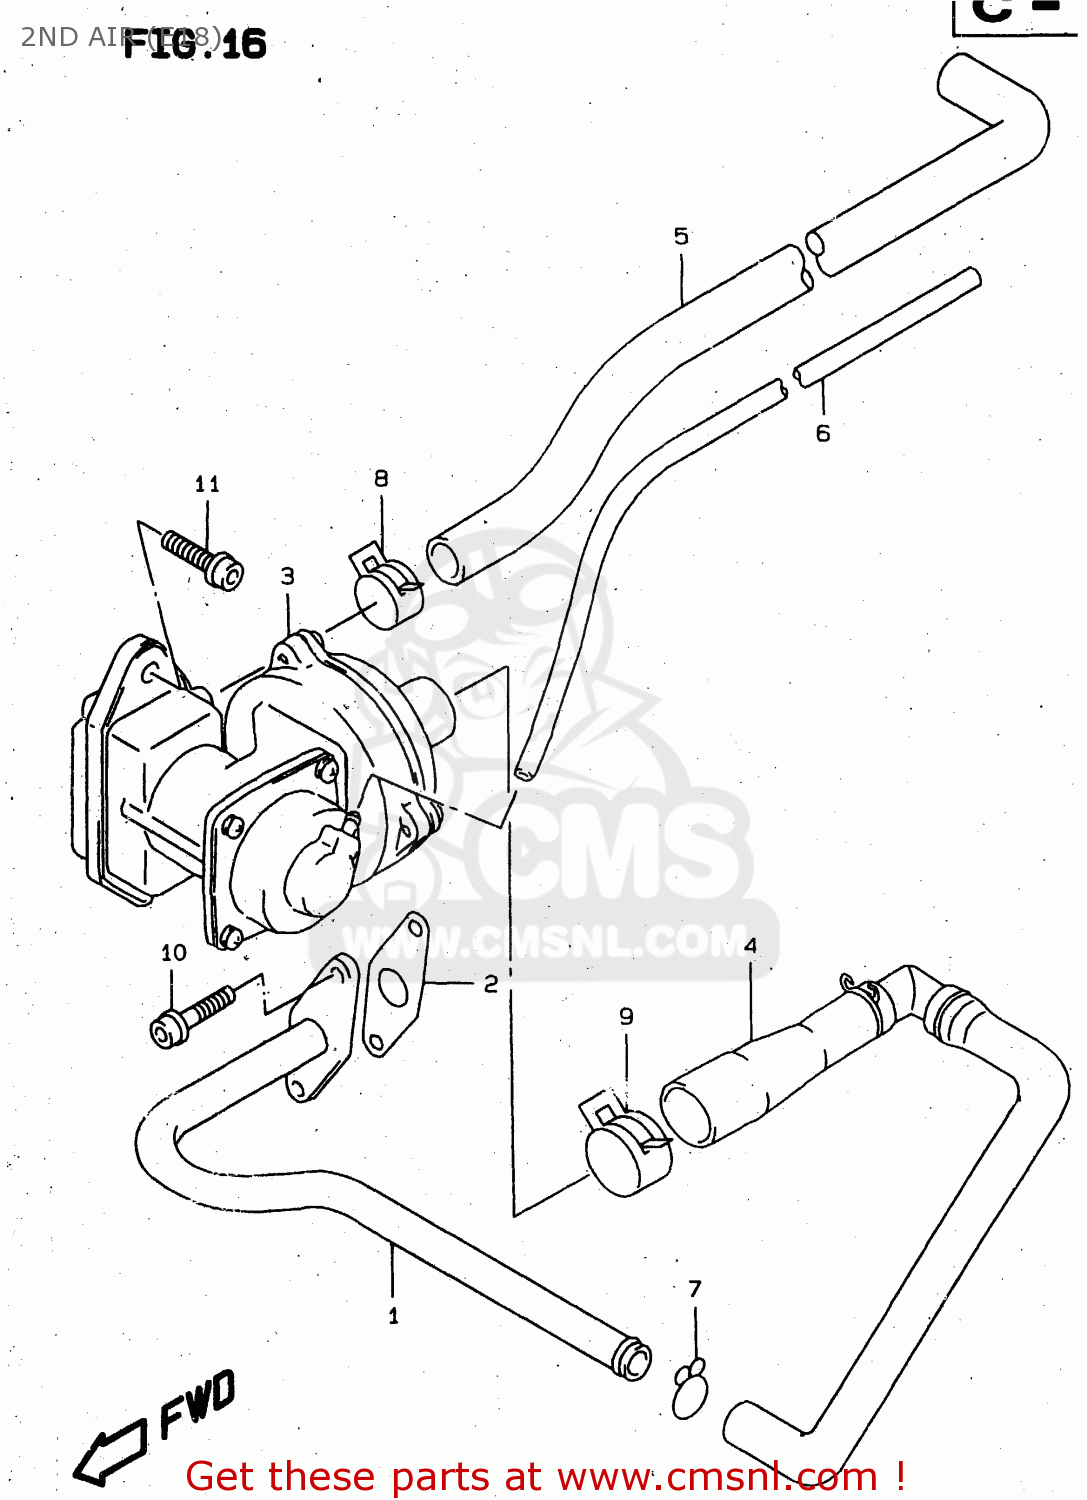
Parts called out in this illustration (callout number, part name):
1	PIPE, 2ND AIR
2	GASKET,SECOND AIR PIPE (N (NAS)
3	VALVE ASSY,2ND AIR REED
4	HOSE ASSY, 2ND AIR
5	HOSE,2ND AIR INLET
6	HOSE(4X7X600)
7	CLIP
8	CLIP
9	CLIP,SECOND AIR HOSE
10	BOLT MAGNETO S
11	BOLT
